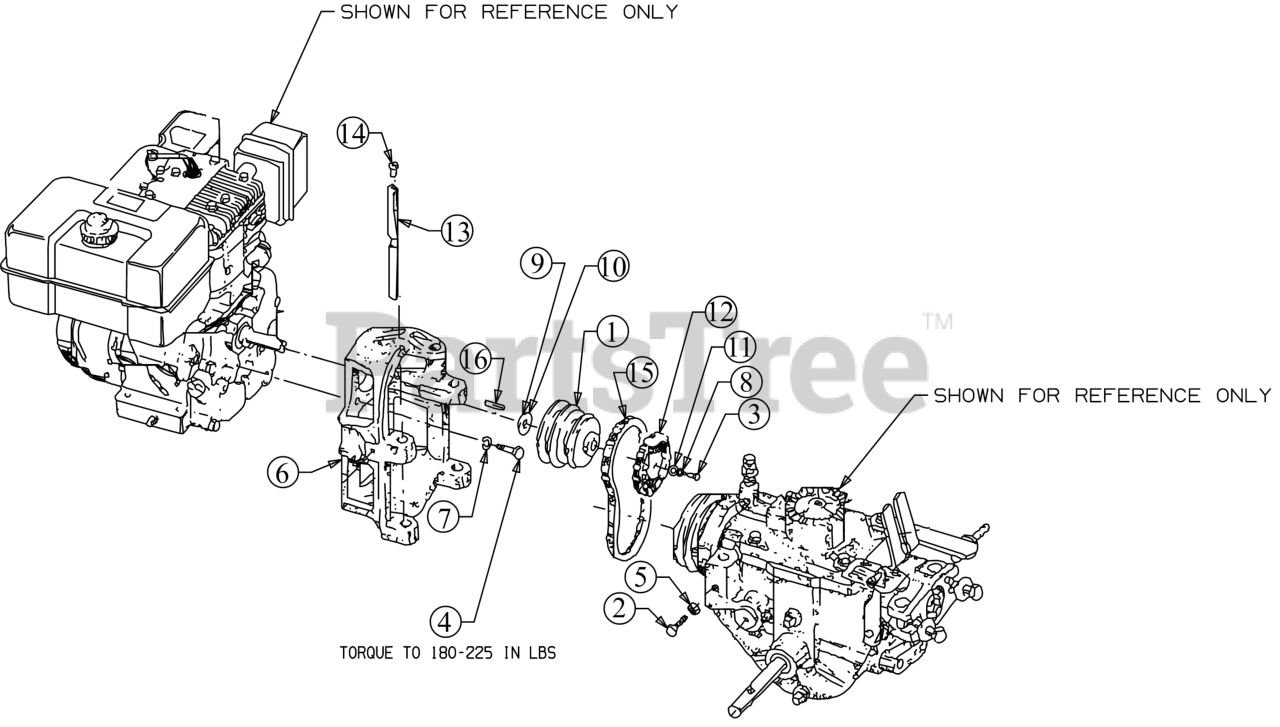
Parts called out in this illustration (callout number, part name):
2	SCREW 5/16-18 X 1.0 GR5
3	SCREW 3/8-24 X 1.75 GR5
4	SCREW 5/16-24 X 1.25 GR5
5	HEX NUT 5/16-18
6	MOTOR MOUNT (POWDER BLACK)
7	LOCK WASHER 5/16
8	LOCK WASHER 3/8
9	SHIM 1.0X.7656X.062
10	FLAT WASHER .766 X 1.000 X .031
11	FLAT WASHER .406ID X1.0 OD
12	REVERSE DISC
13	ENGINE MOUNTING BAR
14	PLUG-CAP (RED)
15	DRIVE BELT FORWARD 22.14''
